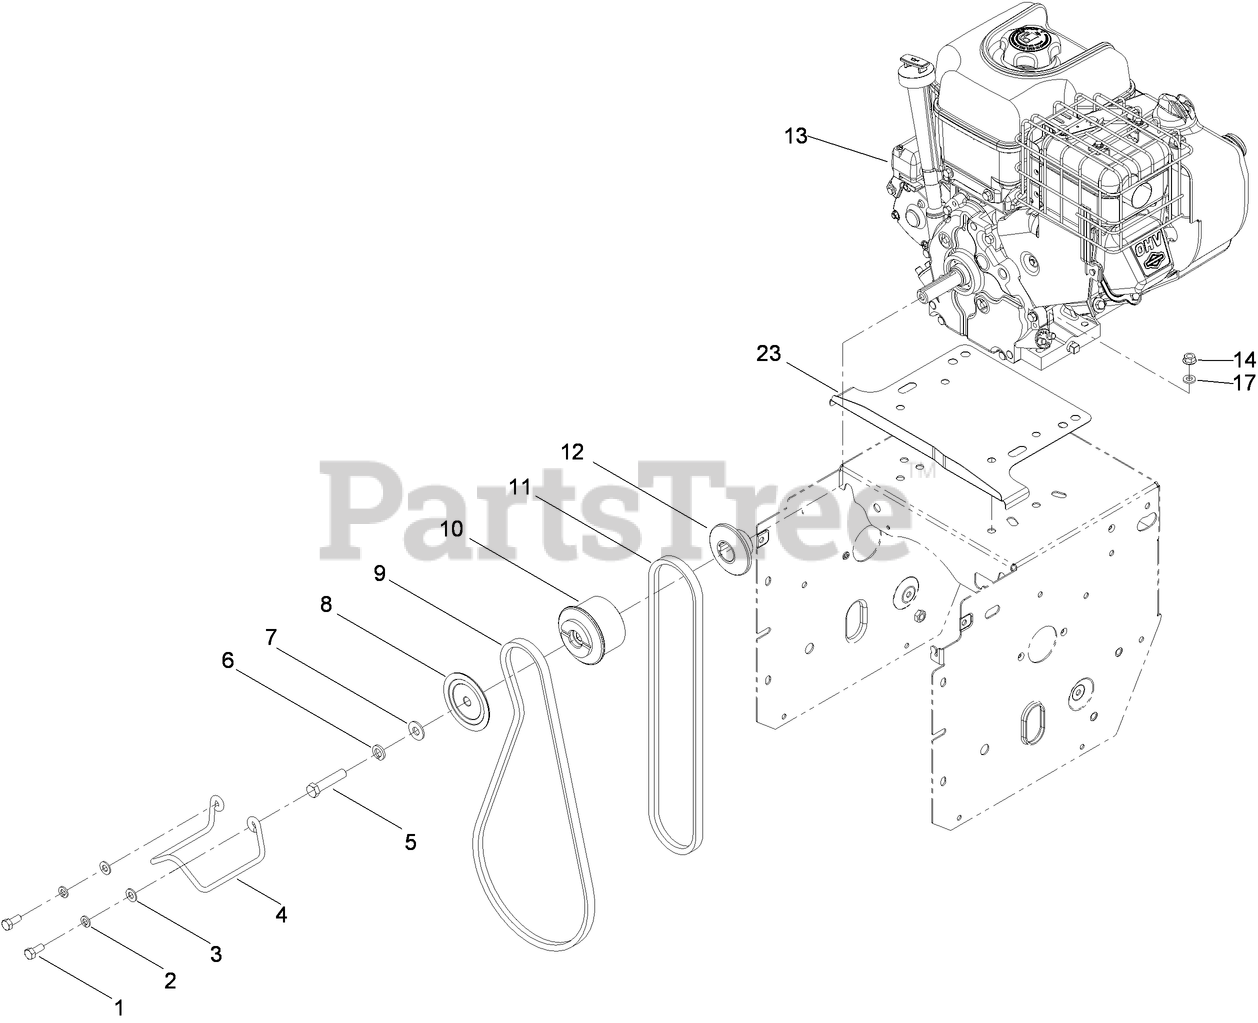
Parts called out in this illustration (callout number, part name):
1	SCREW-HH
2	WASHER-LOCK
3	WASHER-PLAIN
5	SCREW-HH
6	WASHER-LOCK
7	WASHER-FLAT
8	SHEAVE-HALF, IMPELLER
9	BELT-V
10	PULLEY-ENGINE, CENTER
11	V BELT-TRACTION
12	SHEAVE-HALF, TRACTION
14	NUT-HF
17	WASHER-FLAT
23	SHIELD-DRIVE
